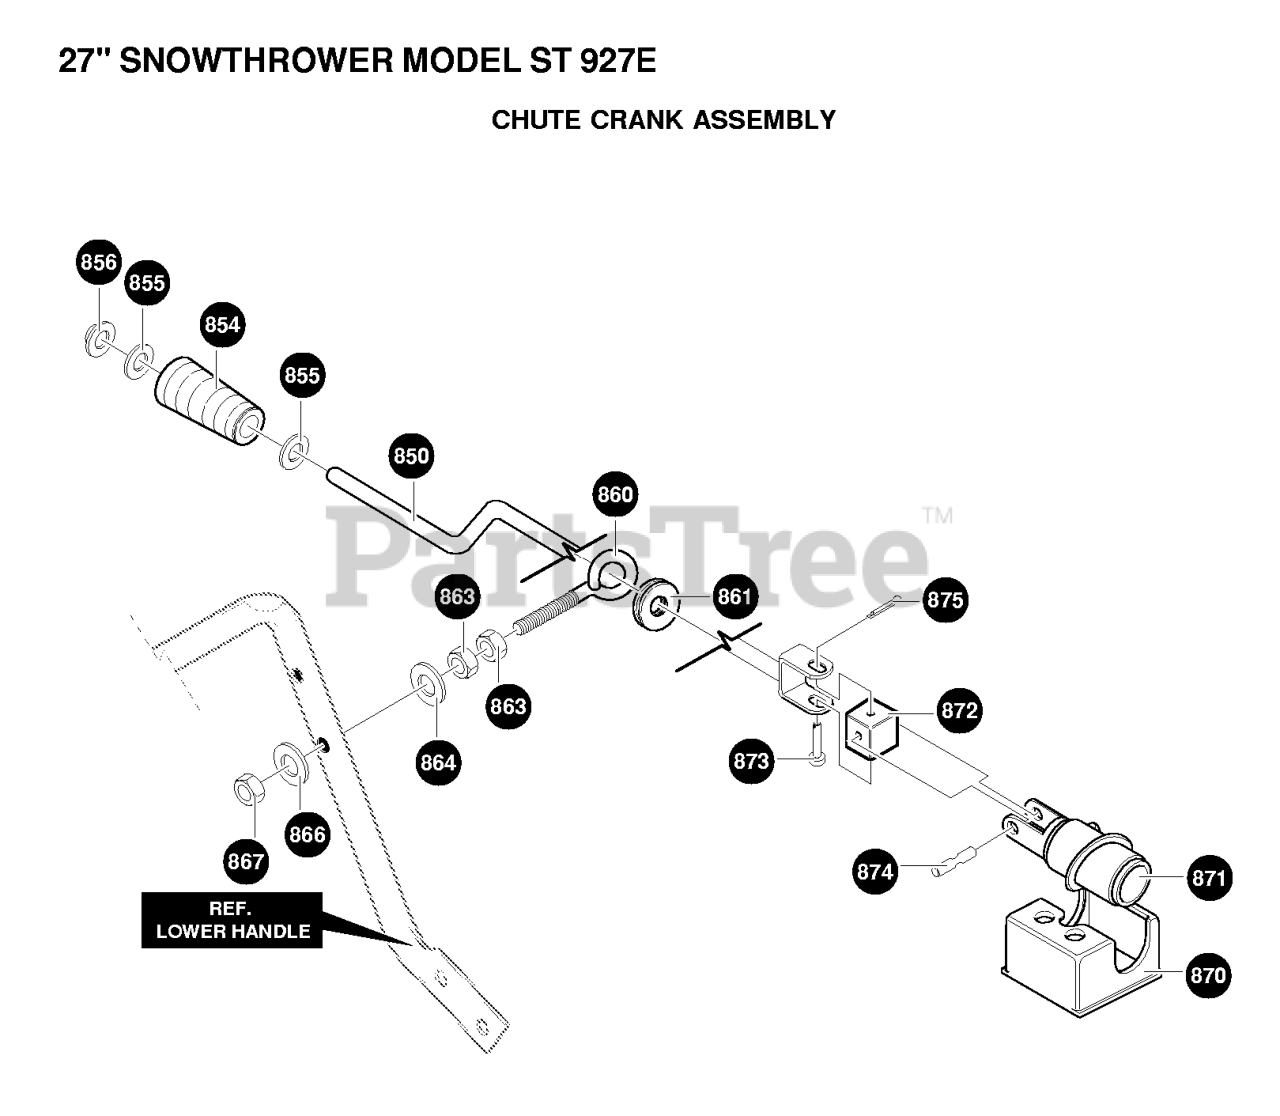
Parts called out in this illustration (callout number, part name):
850	CRANK ASSY W/YOKE
855	WASHER, FLAT .406X .81X.
856	NUT-PUSH ON 3/8"
864	WASHER, FLAT .406X .81X.
866	WASHER, FLAT .406X .81X.
867	NUT, 3/8-16 HEXNYL
870	BRACKET, WORM MOUNTING
871	WORM GEAR CHUTE ROTATE 585196
872	BLOCK, UNIV
873	PIN, CLEVIS
874	PIN, UNIV JOINT
875	COTTER PIN .06X.50
